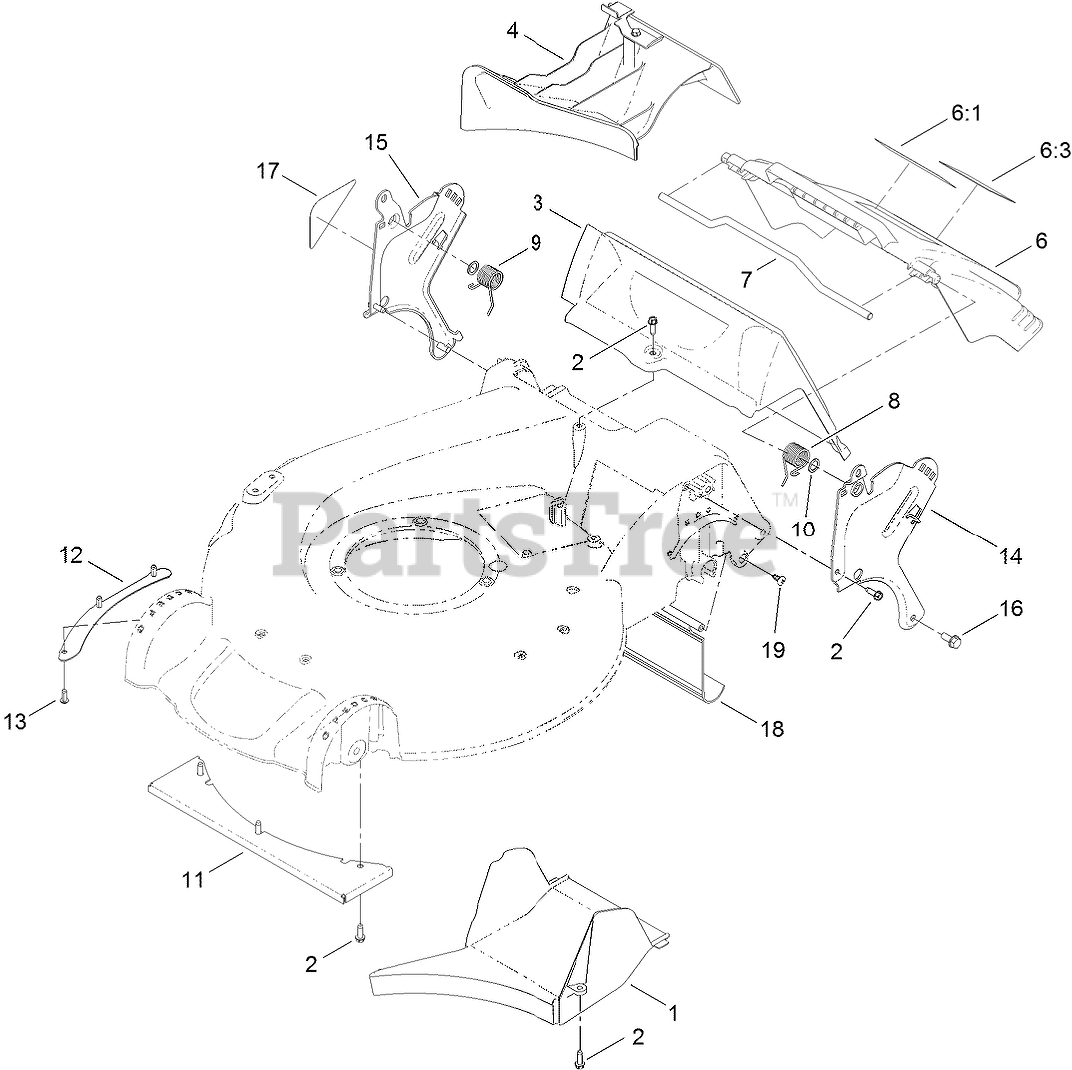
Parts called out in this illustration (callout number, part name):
1	TUNNEL-DISCHARGE
2	SCREW-HWHTF
4	MULCH PLUG ASM
6	REAR DOOR ASM
6:1	DECAL-WARNING
6:3	DECAL-WARNING
7	ROD-DEFLECTOR
8	SPRING-TORSION
9	SPRING-TORSION
10	WASHER-NYLON
11	PLATE-COVER, FRONT
12	SHEET-LIP
13	SCREW
14	BRACKET-HANDLE, LH
15	BRACKET-HANDLE, RH
16	SCREW-HWHTF
17	DECAL-INSTRUCTION
18	SHIELD-TRAILING
19	SCREW-PTH
